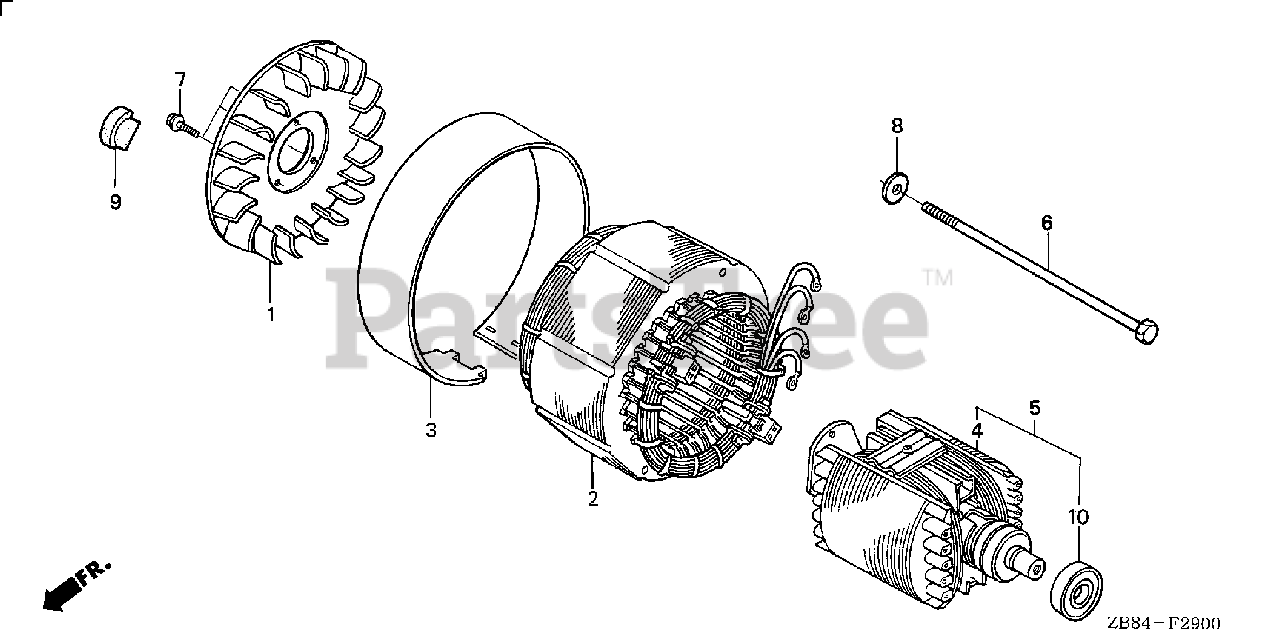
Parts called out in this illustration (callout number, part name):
1	FAN, GENERATOR COOLING
2	STATOR ASSY.
3	COVER, STATOR
5	ROTOR
6	BOLT, HEX. (10X250)
7	SCREW, TAPPING (5X14)
8	WASHER (10.5MM)
9	GROMMET, CRANKCASE
10	BEARING ASSY. (6204)
